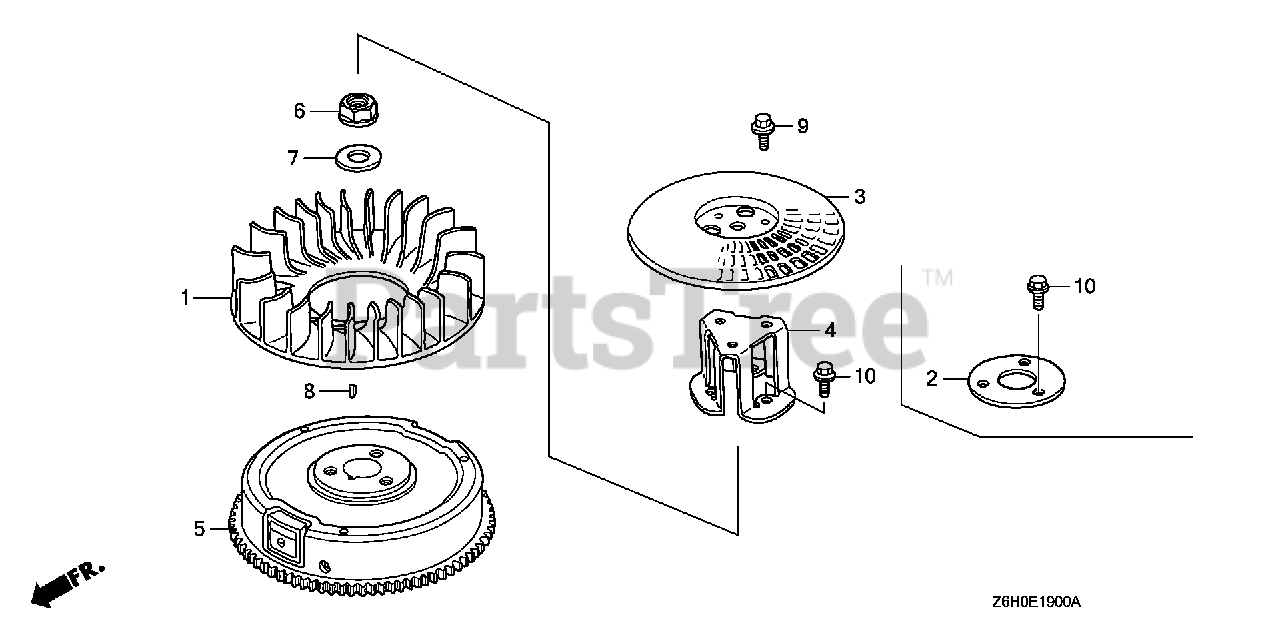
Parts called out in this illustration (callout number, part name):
1	FAN, COOLING
3	GRID, SCREEN
4	HOLDER, SCREEN GRID
6	NUT, FLANGE (20MM)
7	WASHER (20MM)
8	KEY, SPECIAL WOODRUFF (25X18)
9	BOLT, FLANGE (6X12)
10	BOLT, FLANGE (8X16)
